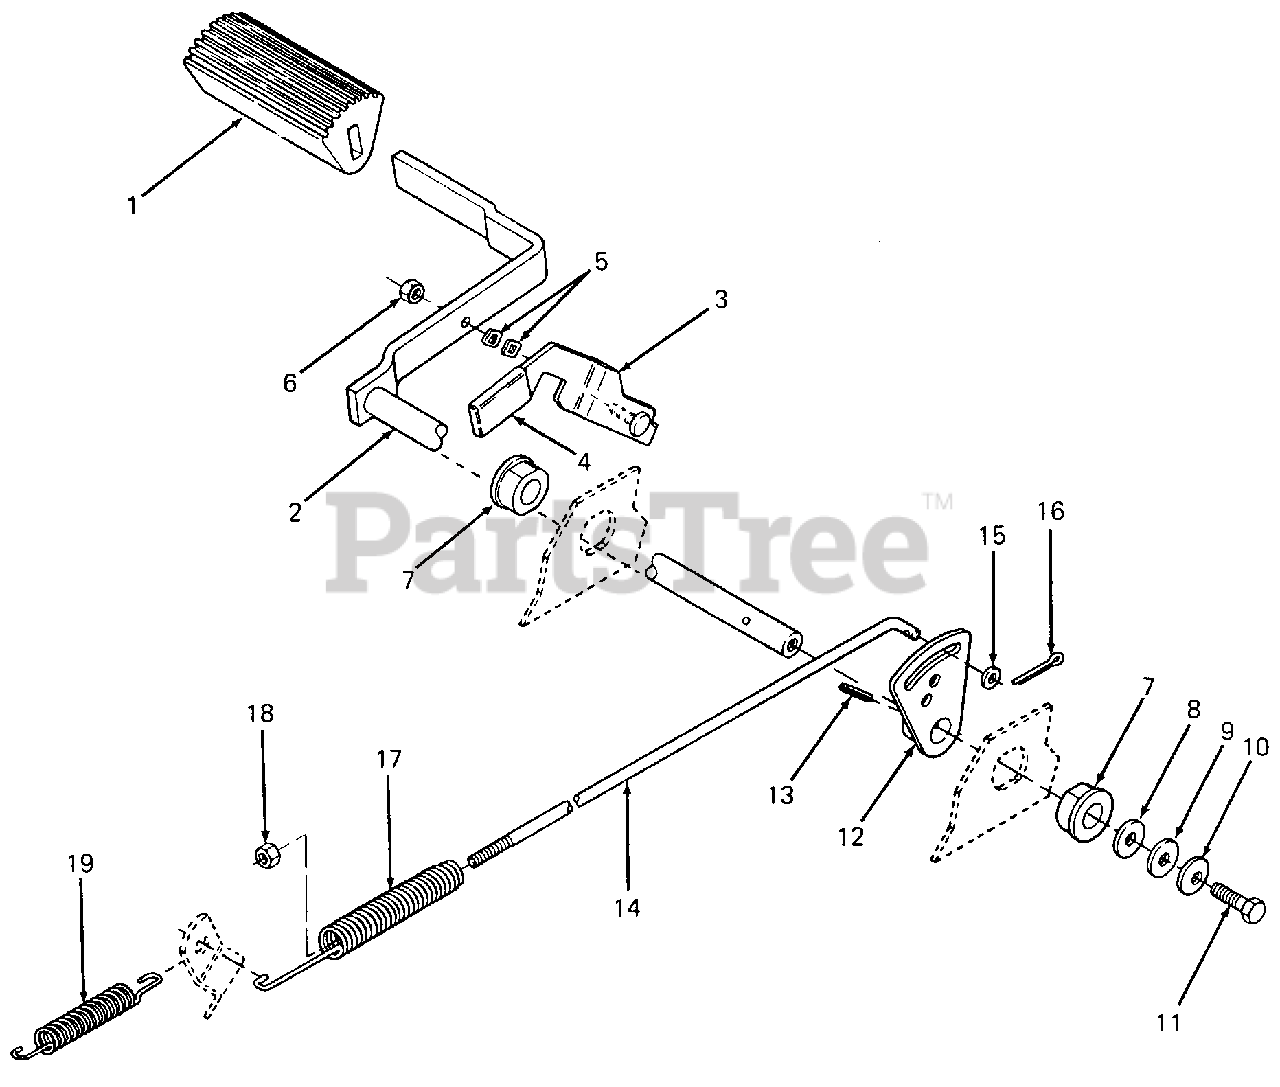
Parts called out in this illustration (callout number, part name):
1	Pad, Foot
5	Washer, Wave
6	Nut, Hex Insert Lock, 1/4-20
7	Bearing, Flange
8	Washer, Flat, .635 X 1.12 X .090 Thk
9	Washer, Flat, .26 X .93 X .120 Thk
10	Washer, Bell, .265 X .75 X .062 Thk
11	Screw, Hex Cap, 1/4-20 X .75 Lg GR5
12	Cam, Brake
13	Pin, Spiral Spring, 3/16 Dia X 1.5 Lg
14	Rod, Brake
15	Washer, Flat, .281 X .73 X .063 Thk
16	Pin, Cotter, 3/32 X .75 Lg
17	Spring, Ext
18	Nut, Hex Patch, 1/4-20
19	Spring, Brake Return
